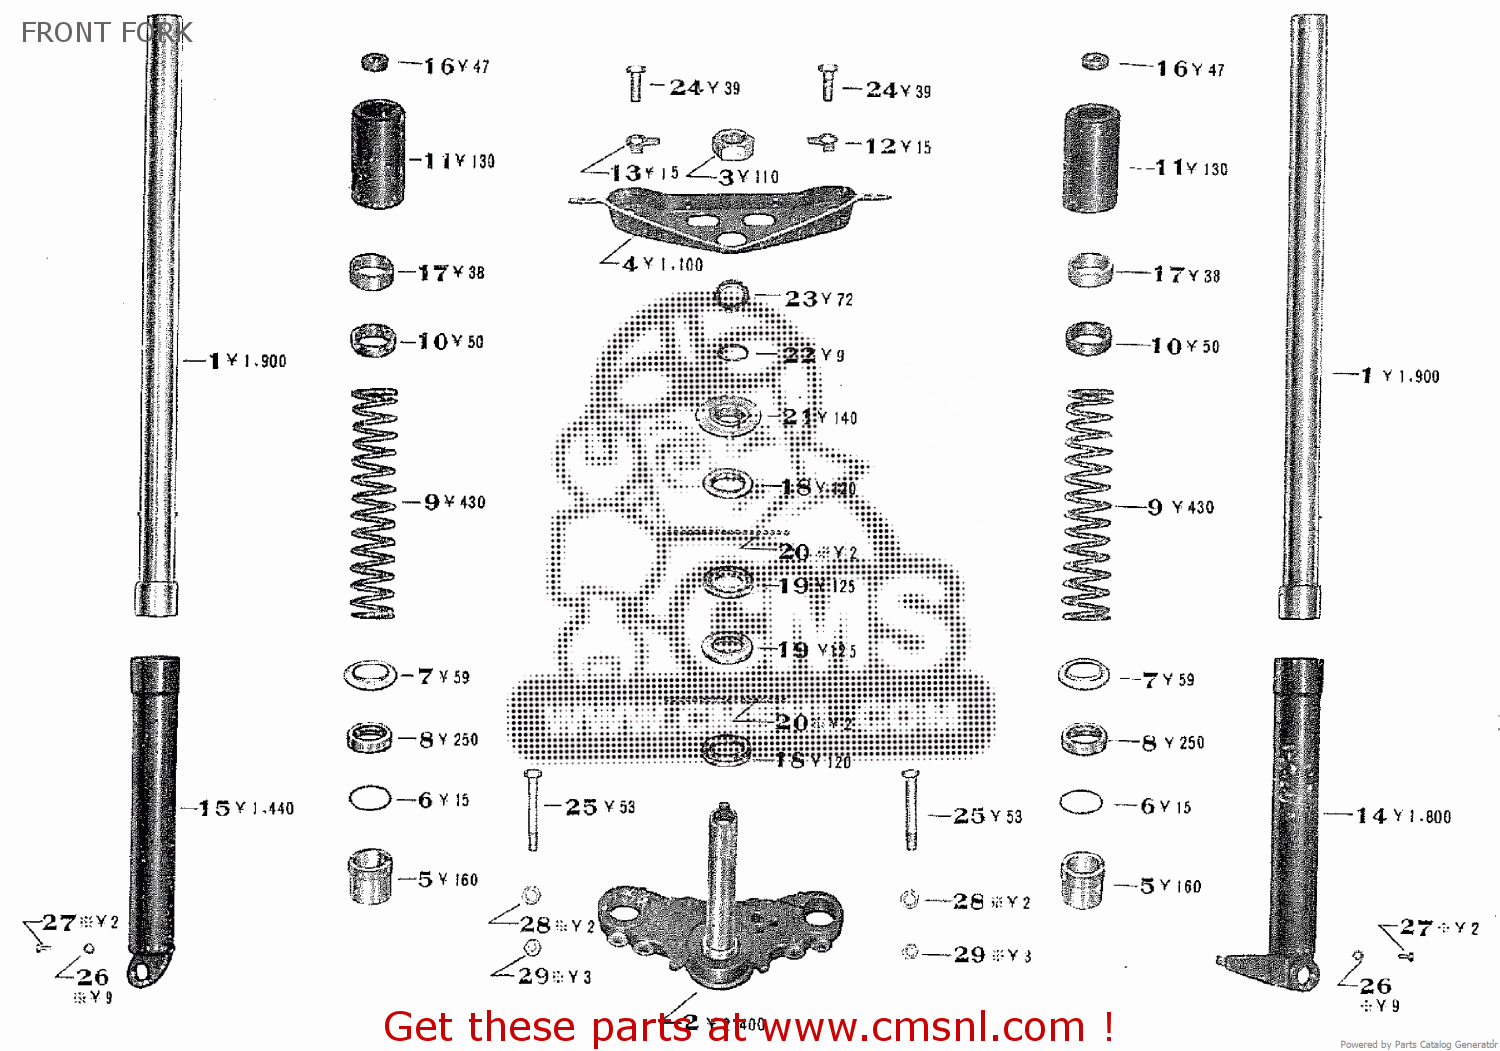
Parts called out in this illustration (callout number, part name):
1	INNER TUBE COMP.
2	UNDER BRACKET COMP.
3	UPPER BRACKET SET NUT
4	UPPER BRACKET
5	SLIDE METAL
6	WASHER
7	SPRING SHEET (A)
8	OIL SEAL
9	SPRING
10	SPRING SHEET (B)
11	SPRING COVER
12	RIGHT UPPER BRACKET SET WASHER
13	LEFT UPPER BRACKET SET WASHER
14	RIGHT OUTER TUBE COMP.
15	LEFT OUTER TUBE COMP.
16	INNER TUBE PACKING
17	VINYL PIPE
18	STEERING OUTER RACE
19	STEERING INNER RACE
20	STEERING HEAD STEEL BALL
21	STEERING NUT
22	STEERING SHAFT WASHER
23	STEERING SHAFT LOCK NUT
24	UPPER BRACKET SET BOLT
25	UNDER BRACKET SET BOLT
26	DRAIN PLUG PACKING
27	6X10 CROSS SCREW
28	10MM SPRING WASHER
29	10MM HEXAGON NUT
